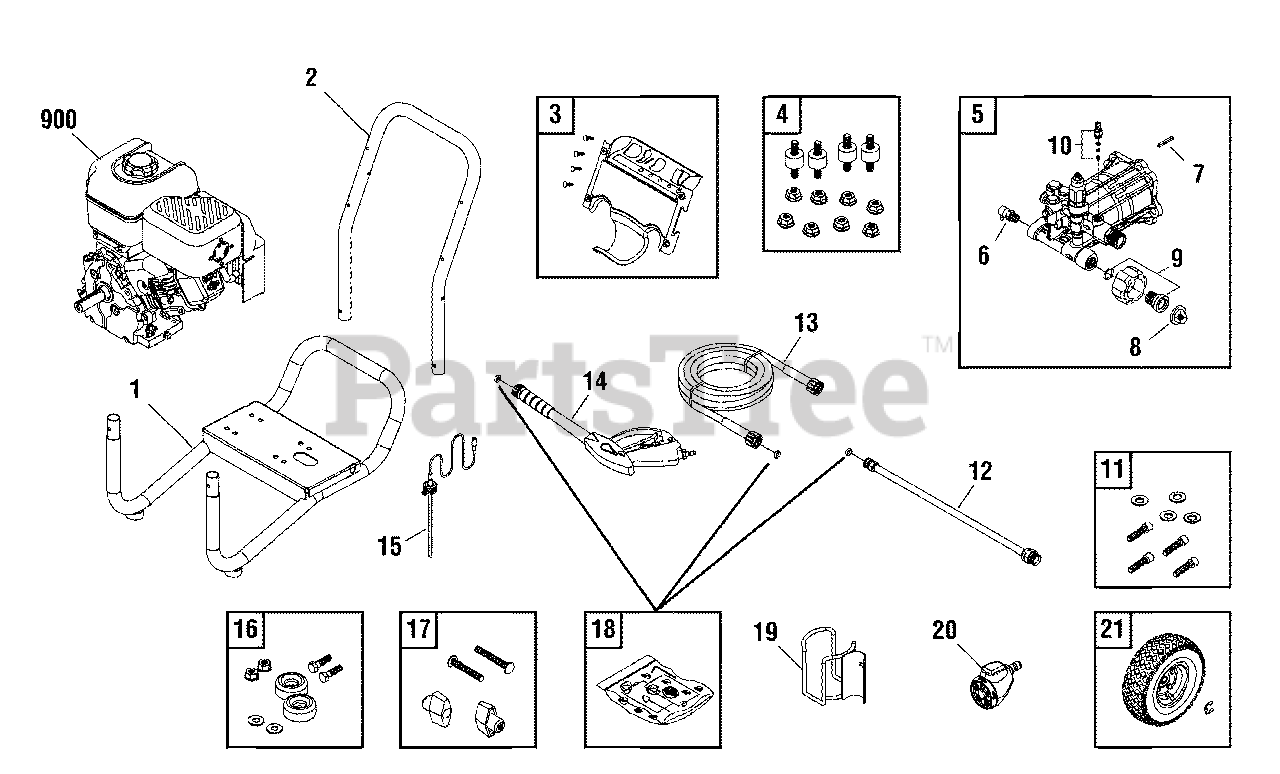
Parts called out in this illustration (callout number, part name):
4	KIT, Vibration Mount
5	PUMP
6	VALVE, Thermal Relief
8	FILTER, Garden Hose
9	KIT, Water Inlet
10	KIT, Chemical Injection
11	KTI, Hardware, Pump Mounting
12	EXTENSION, QC
14	GUN
16	MOUNT, Vibration
17	KTI, Hardware, Handle
18	KIT, O-Ring
20	NOZZLE, QC
